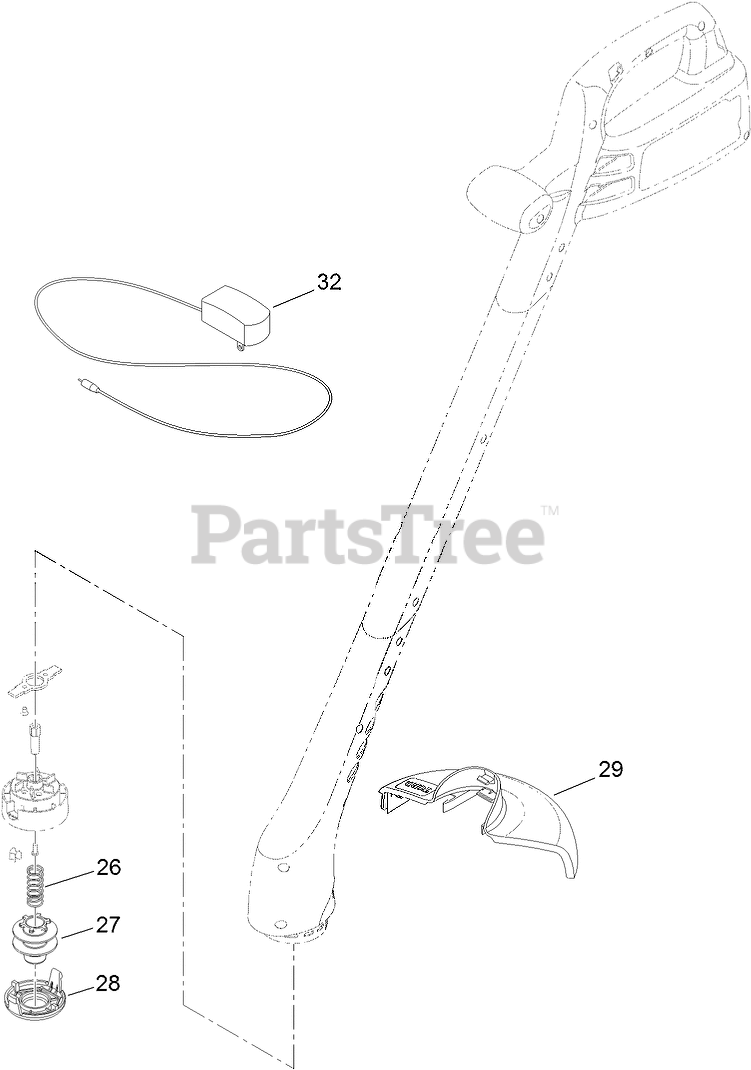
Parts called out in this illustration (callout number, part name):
26	SPRING-COMPRESSION
27	SPOOL ASM
28	CAP-SPOOL, 7 INCH
29	8 INCH SHIELD ASM
32	CHARGER-BATTERY, 12V
